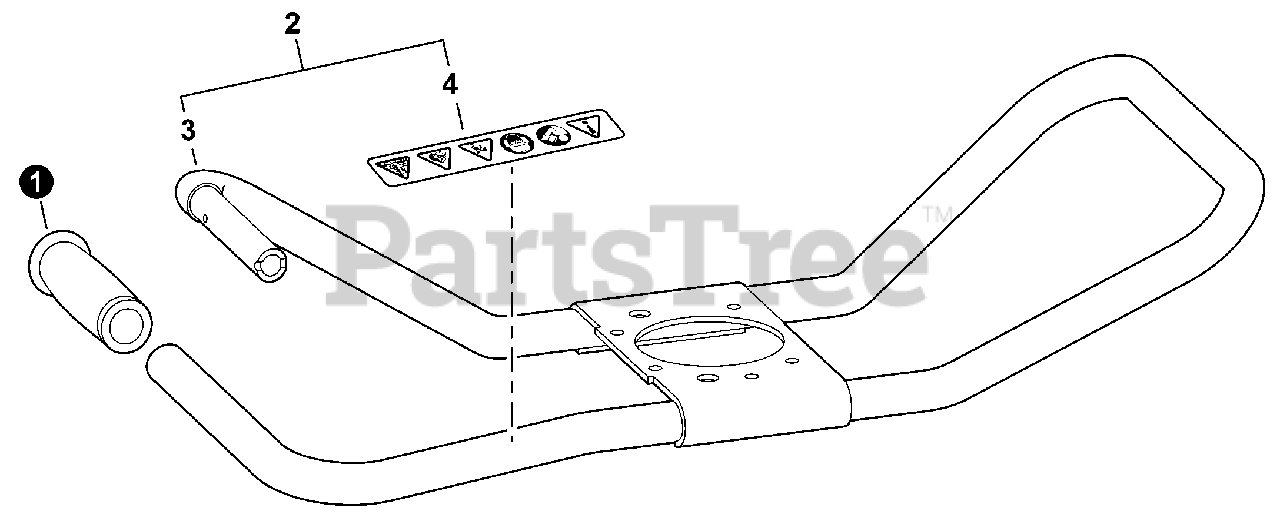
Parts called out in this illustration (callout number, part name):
1	GRIP, HANDLE
2	HANDLE SET
3	HANDLE ASSY
4	LABEL, CAUTION
